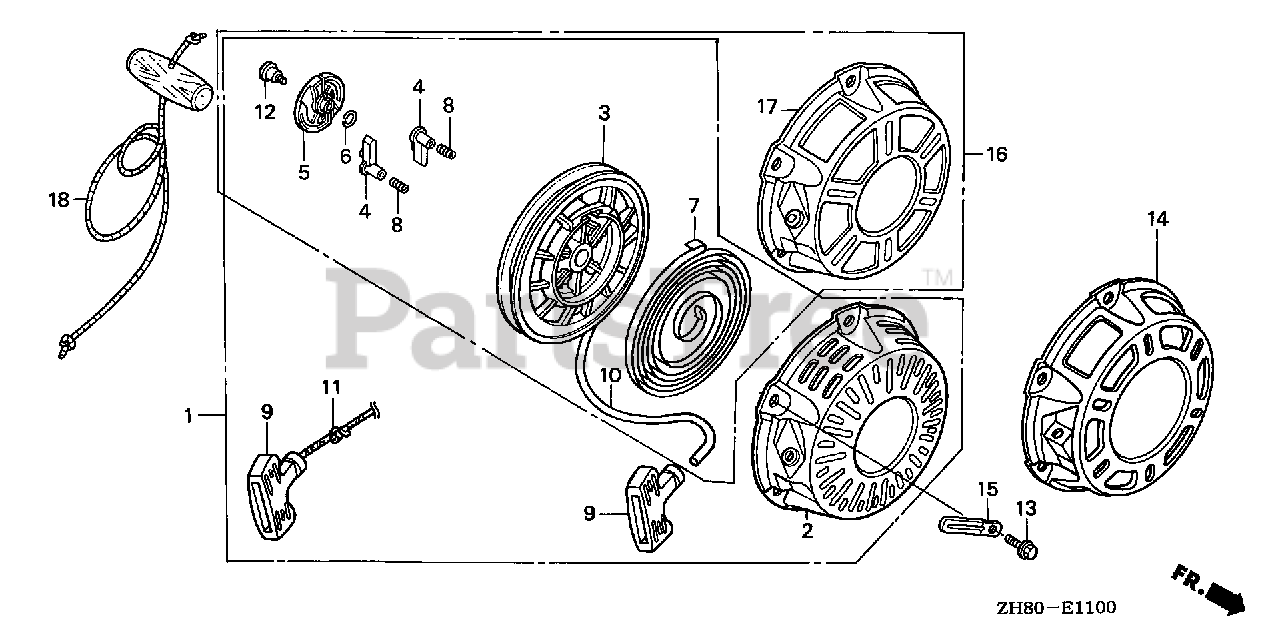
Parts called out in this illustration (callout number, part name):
1	STARTER ASSY., RECOIL *R280* (POWER RED)
1	STARTER ASSY., RECOIL *NH1* (BLACK)
2	CASE, RECOIL STARTER *R280* (POWER RED)
2	CASE, RECOIL STARTER *NH1* (BLACK)
3	REEL, RECOIL STARTER (NATURAL)
4	RATCHET, STARTER
5	GUIDE, RATCHET
6	SPRING, FRICTION
7	SPRING, RECOIL STARTER
8	SPRING, RETURN
9	GRIP, STARTER
9	KNOB, RECOIL STARTER
10	ROPE, RECOIL STARTER
12	SCREW, SETTING
13	BOLT, FLANGE (6X10)
